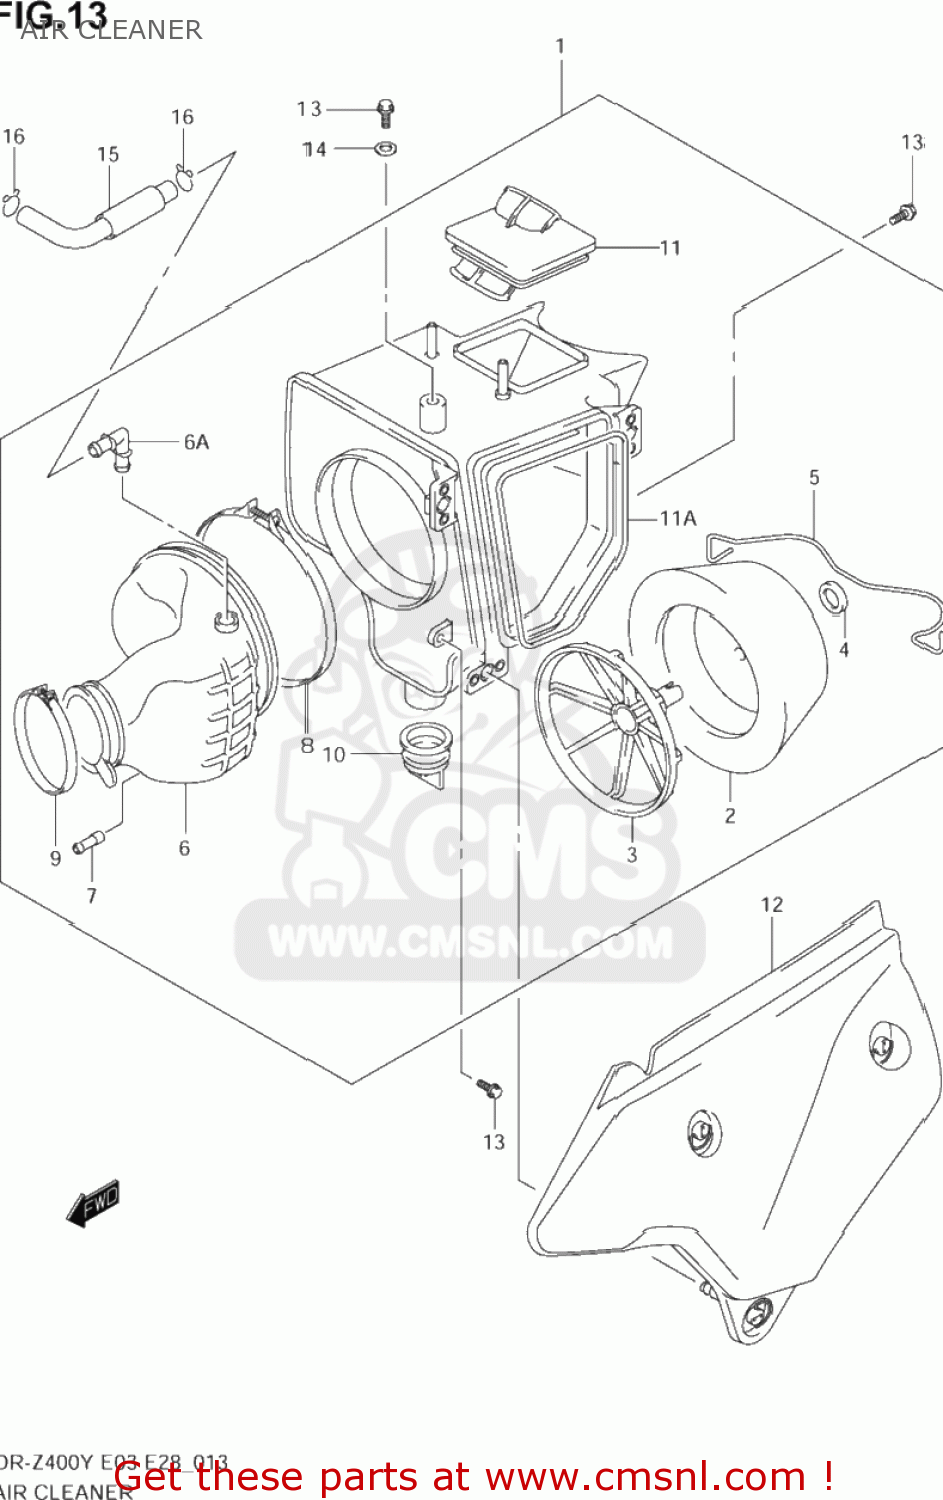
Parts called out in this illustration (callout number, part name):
1	CLEANER,AIR
2	FILTER ASSY
3	HOLDER,FILTER
4	SPACER
5	SPRING
6	TUBE,OUTLET
6A	JOINT
7	UNION
8	CLAMP
9	CLAMP
10	VALVE
11	TUBE,INLET
11A	GASKET,AIR CLEANER (NAS)
12	CAP,AIR CLEANER
13	BOLT
14	WASHER
15	TUBE COMP,BREATHER
16	CLIP
